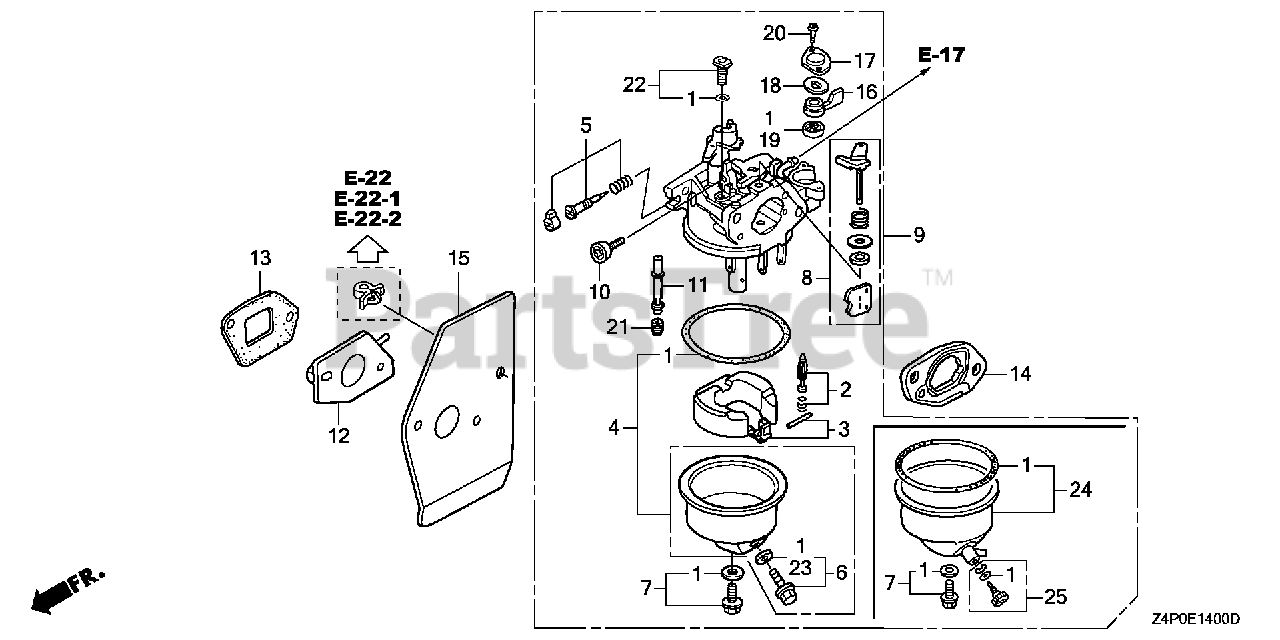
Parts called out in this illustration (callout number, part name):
1	GASKET SET
2	VALVE SET, FLOAT (CARBURETOR NO.) (SEAT NOT INCLUDED)
3	FLOAT SET
4	CHAMBER SET, FLOAT
6	SCREW SET, DRAIN
9	CARBURETOR ASSY. (BEA2U A)
10	SCREW, THROTTLE STOP
11	NOZZLE, MAIN
12	INSULATOR, CARBURETOR
13	GASKET, INSULATOR
13	GASKET, INSULATOR (NINGBO SIL GASKET)
14	SPACER, CARBURETOR
15	GASKET, CARBURETOR
15	GASKET, CARBURETOR (NINGBO SIL GASKET)
16	LEVER, PETCOCK
17	PLATE, LEVER SETTING (CARBURETOR NO.)
18	SPRING, PETCOCK LEVER (CARBURETOR NO.)
19	GASKET, VALVE
20	SCREW, PAN (3X6)
21	JET, MAIN (#60)
21	JET, MAIN (#62)
21	JET, MAIN (#65)
22	JET SET, PILOT (#40) (ADVENTURE GREEN) (CARBURETOR NO.)
23	WASHER, PLAIN (6.2X10.7 DRAIN) (CARBURETOR NO.)
